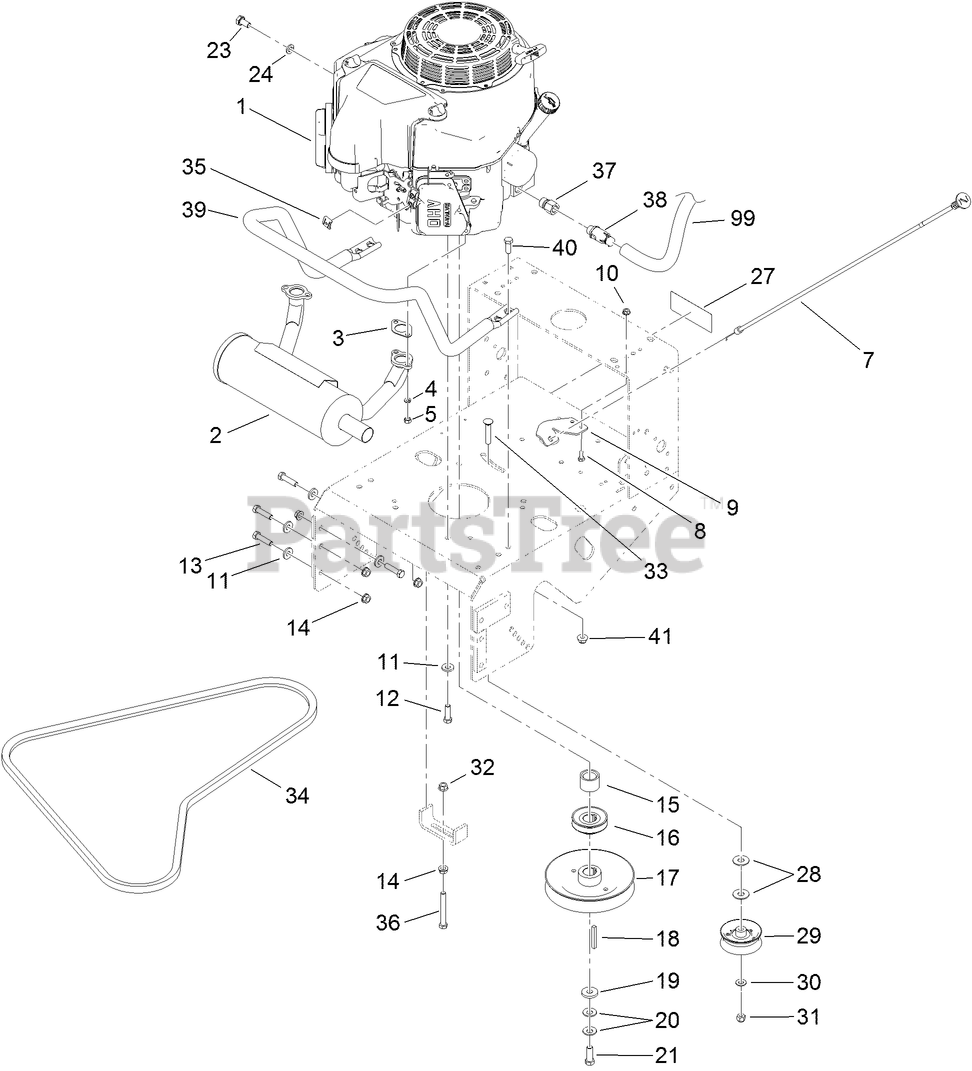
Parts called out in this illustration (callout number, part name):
2	MUFFLER-HORIZONTAL, OFFSET
3	GASKET-EXHAUST
4	WASHER-LOCK
7	CABLE-CHOKE
8	SCREW-HH
9	BRACKET-CABLE, CHOKE
10	NUT-HF
11	WASHER-BELLEVILLE
12	SCREW-HH
13	SCREW-HH
14	NUT-HHF, WHIZ
15	SPACER-CLUTCH
16	SHEAVE-TRANSMISSION
17	PULLEY ASM
19	WASHER
20	WASHER-SPRING
21	SCREW-HH
23	SCREW-HH
24	SCREW-HH
27	DECAL-WARNING, SULKY
28	WASHER-FLAT
29	PULLEY-IDLER, FLAT
30	WASHER-FLAT
31	NUT-LOCK, NI
32	NUT-HF
33	SCREW-HH
34	BELT-V
35	CLAMP-CABLE
36	SCREW-HH
37	ADAPTER
38	VALVE-DRAIN, OIL
39	GUARD-MUFFLER
40	SCREW-HH
41	NUT-HF, NI
99	HOSE-DRAIN, OIL
